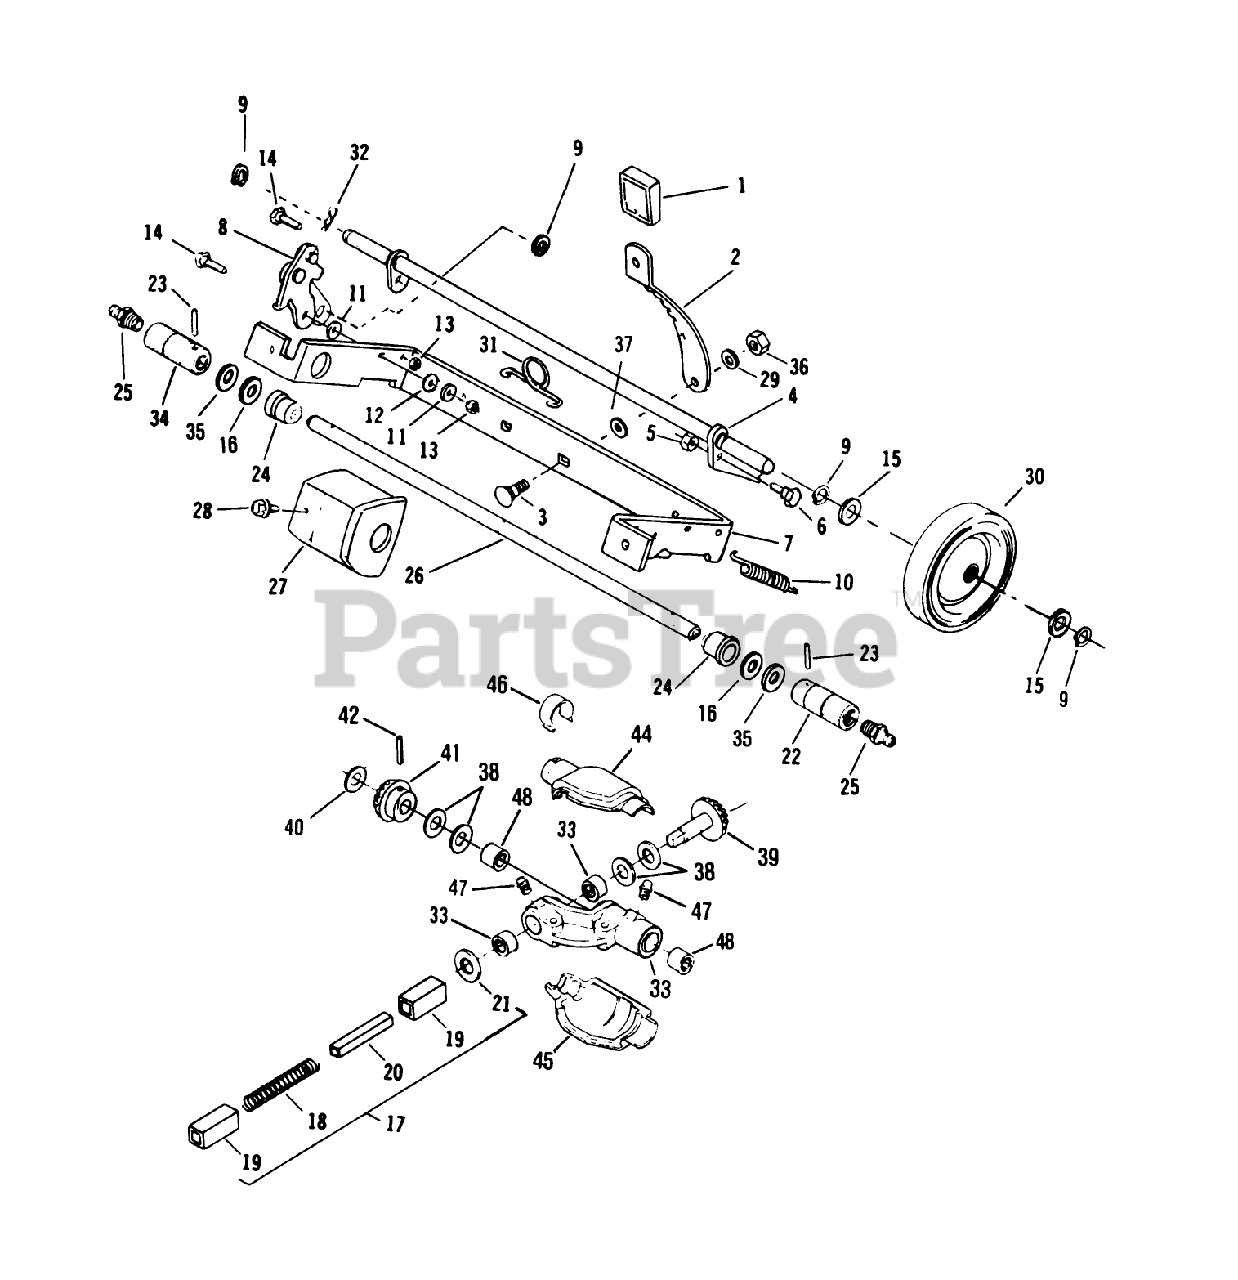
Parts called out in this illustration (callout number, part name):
2	LEVER
4	AXLE & TORQUE LUG ASM
5	LOCKNUT E
6	BOLT RB&W
7	BRACKET *GREEN
8	CLUTCH AY ARGO
9	RET RING
10	SPRING
11	WASHER S
13	STOP NUT
14	BOLT RB&W
15	SPACER
16	THRUST WASHER
18	SPRING
19	BUSHING BKWY
21	WASHER
22	ROLLER-LEFT
24	SLEEVE &BEARING AY
25	GREASE FITTING AP
26	DRIVE SHAFT & TAG
29	WASHER S
31	SPRING N.A.S
36	LOCKNUT E
37	WASHER SPRING LAR
38	THRUST WASHER
39	GEAR BEST
40	WASHER
41	GEAR ADVANCE
42	ROLL PIN
44	GEAR COVER UPPER
47	**FITTING LINCOLN
